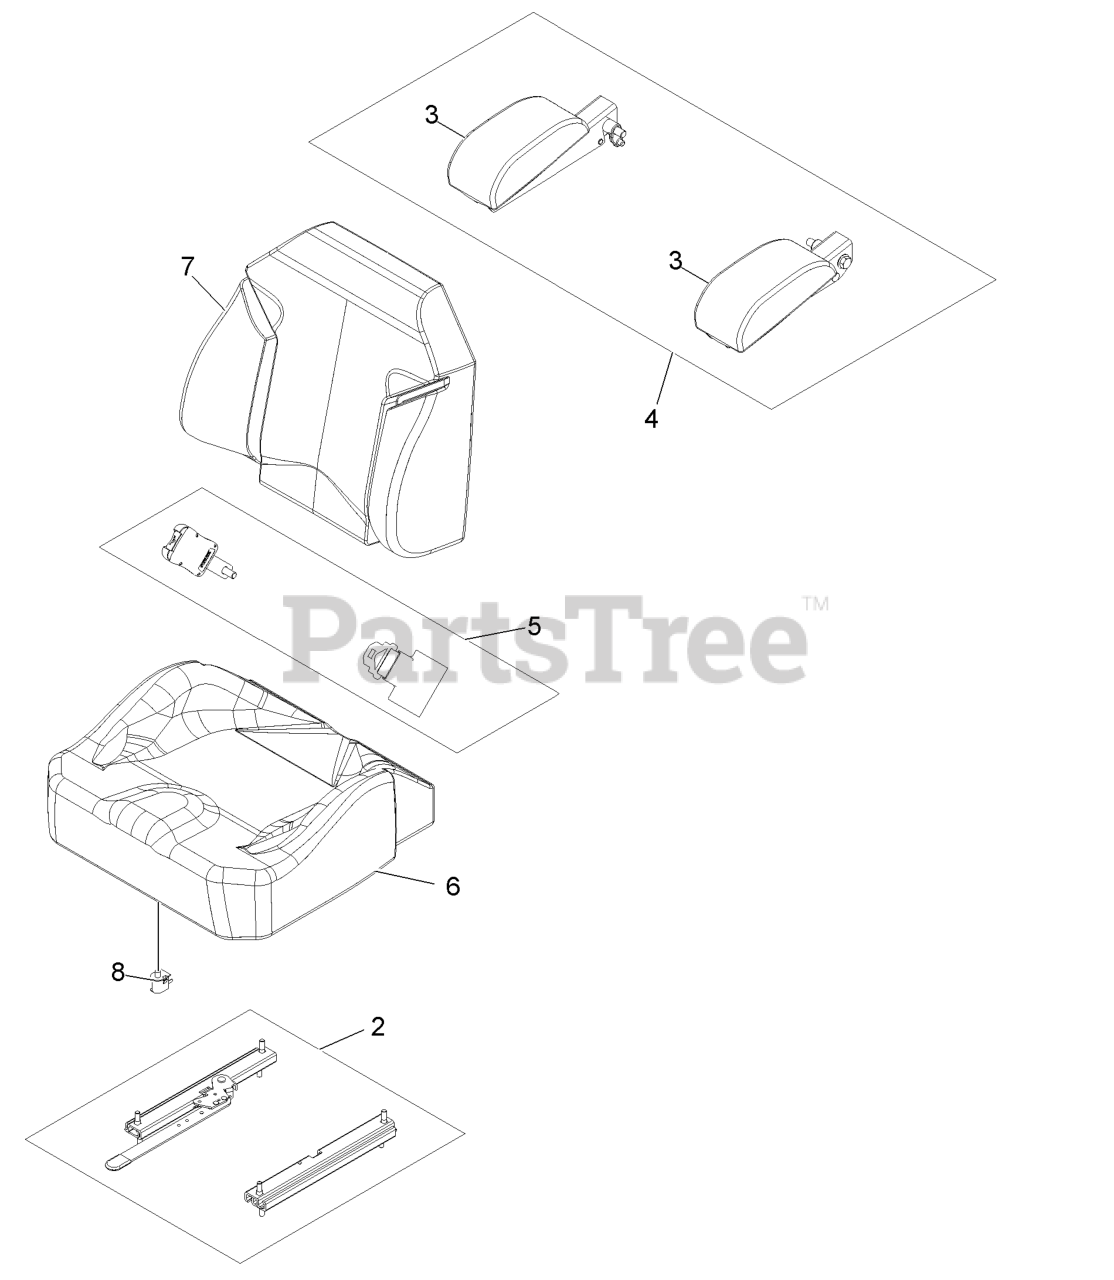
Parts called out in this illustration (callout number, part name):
2	SEAT TRACK SET
3	ARM REST PAD SET
4	ARM REST SET
5	SEAT BELT KIT
6	COVER,CUSHION
7	COVER,BACK
8	SWITCH-BAIL
